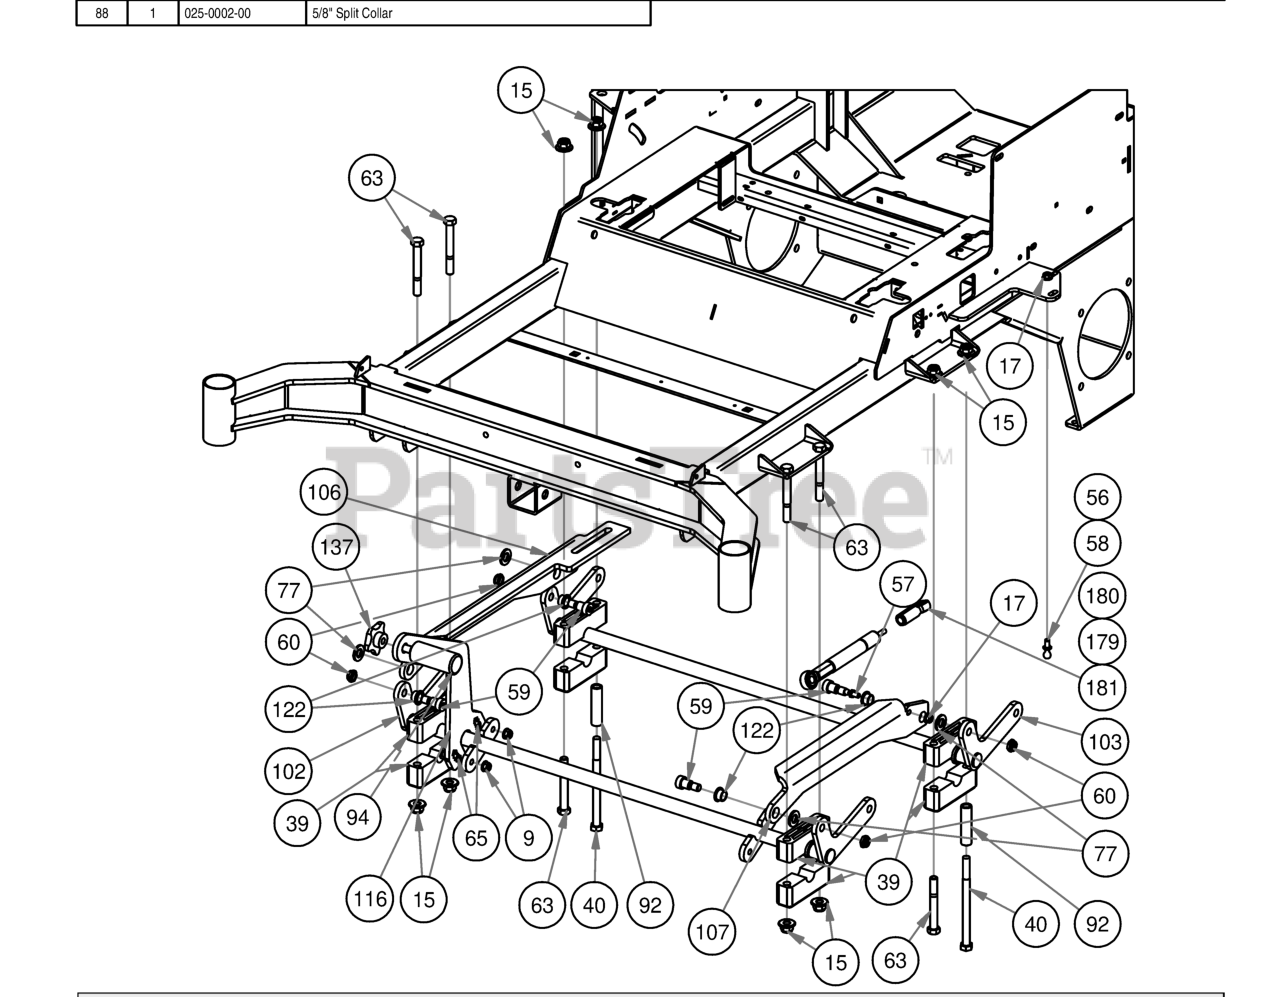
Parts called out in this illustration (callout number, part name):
9	3/8" Nylock Flange Nut
15	1/2-13 Nylon Flange Nut
17	5/16" Flange Nut
39	Pillow Block Assembly
40	1/2 x 7 Hex Bolt Grade 5
56	13mm Damper Ball Stud-Steering
57	10mm Damper Ball Stud-Steering
58	10mm Damper Ball Stud-XP Linkage
59	5/8'' x 5/8'' Shoulder Bolt
60	1/2" Nylcock Nut (1/2 Jam)
63	1/2" x 4" Bolt (Grade 8)
65	3/8" x 1 1/4" Carriage Bolt
77	.630 ID Plastic Washer
92	2019 Deck Stop Spacer
94	Knurled Pedal
102	2019 Outlaw Actuator - Front
103	2019 Outlaw Actuator - Rear
106	2019 Actuator Linkage - Right
107	2019 Actuator Linkage - Left
116	Foot Lift Upright Lever
122	Bronze Bushing - SF - 2024-8
137	Foot Pedal Knob 1/2-13
165	2019 Rigid Frame
179	200 lb Gas Spring- 54" Deck outlaw
180	250lb Gas Spring - 61" Deck
181	300lb Gas Spring - 72" Deck
